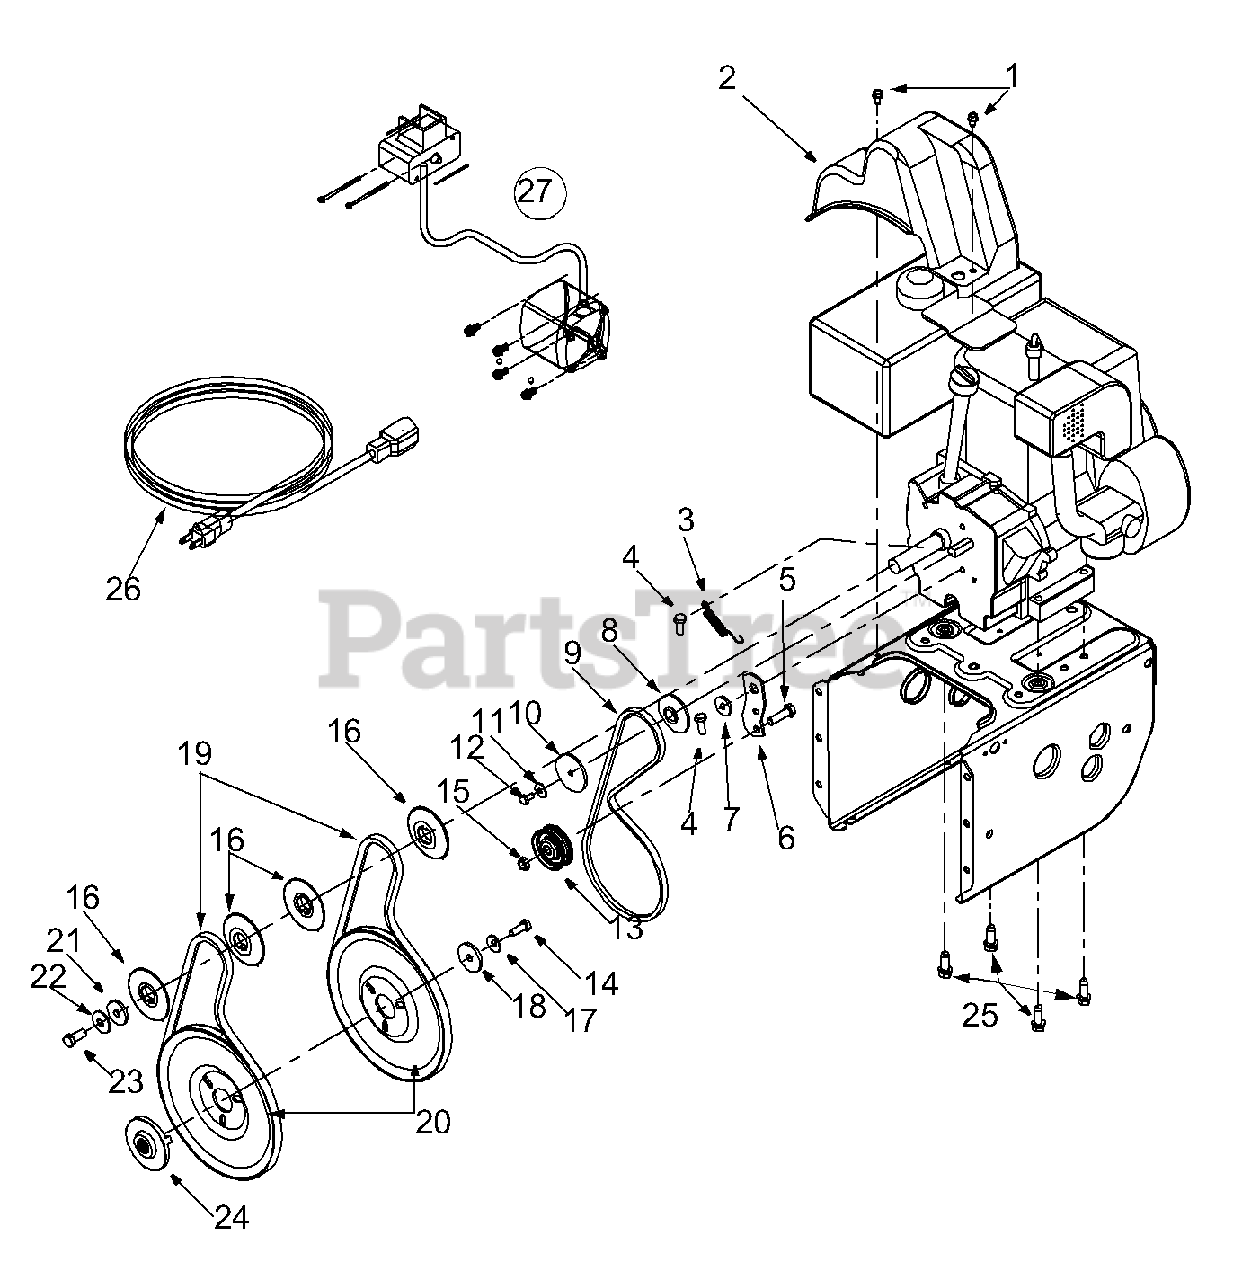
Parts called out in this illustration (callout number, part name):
1	Hex Washer Screw 1/4-20 x .50
2	Belt Cover
3	Extension Spring
4	Hex Screw 5/16-24 x .75
5	Hex Cap Screw 3/8-16 x 1.25
8	Pulley Half
9	V-Belt
10	Pulley Half
11	Bell Washer
12	Hex Cap Screw 1/4-28 x .50
13	Flat Idler
14	Lock Hex Cap Screw 5/16-24
15	Lock Jam Nut 3/8-16
16	Pulley Half
17	Bell Washer
18	Flat Washer
19	Belt
20	Auger Pulley
21	Flat Washer 3/8 x 1.25 OD
22	Bell Washer
23	Hex Cap Screw 3/8-24
24	Adapter Pulley
25	Hex Screw 3/8-16 x 1.0
26	Extension Cord
27	Electric Start Kit
